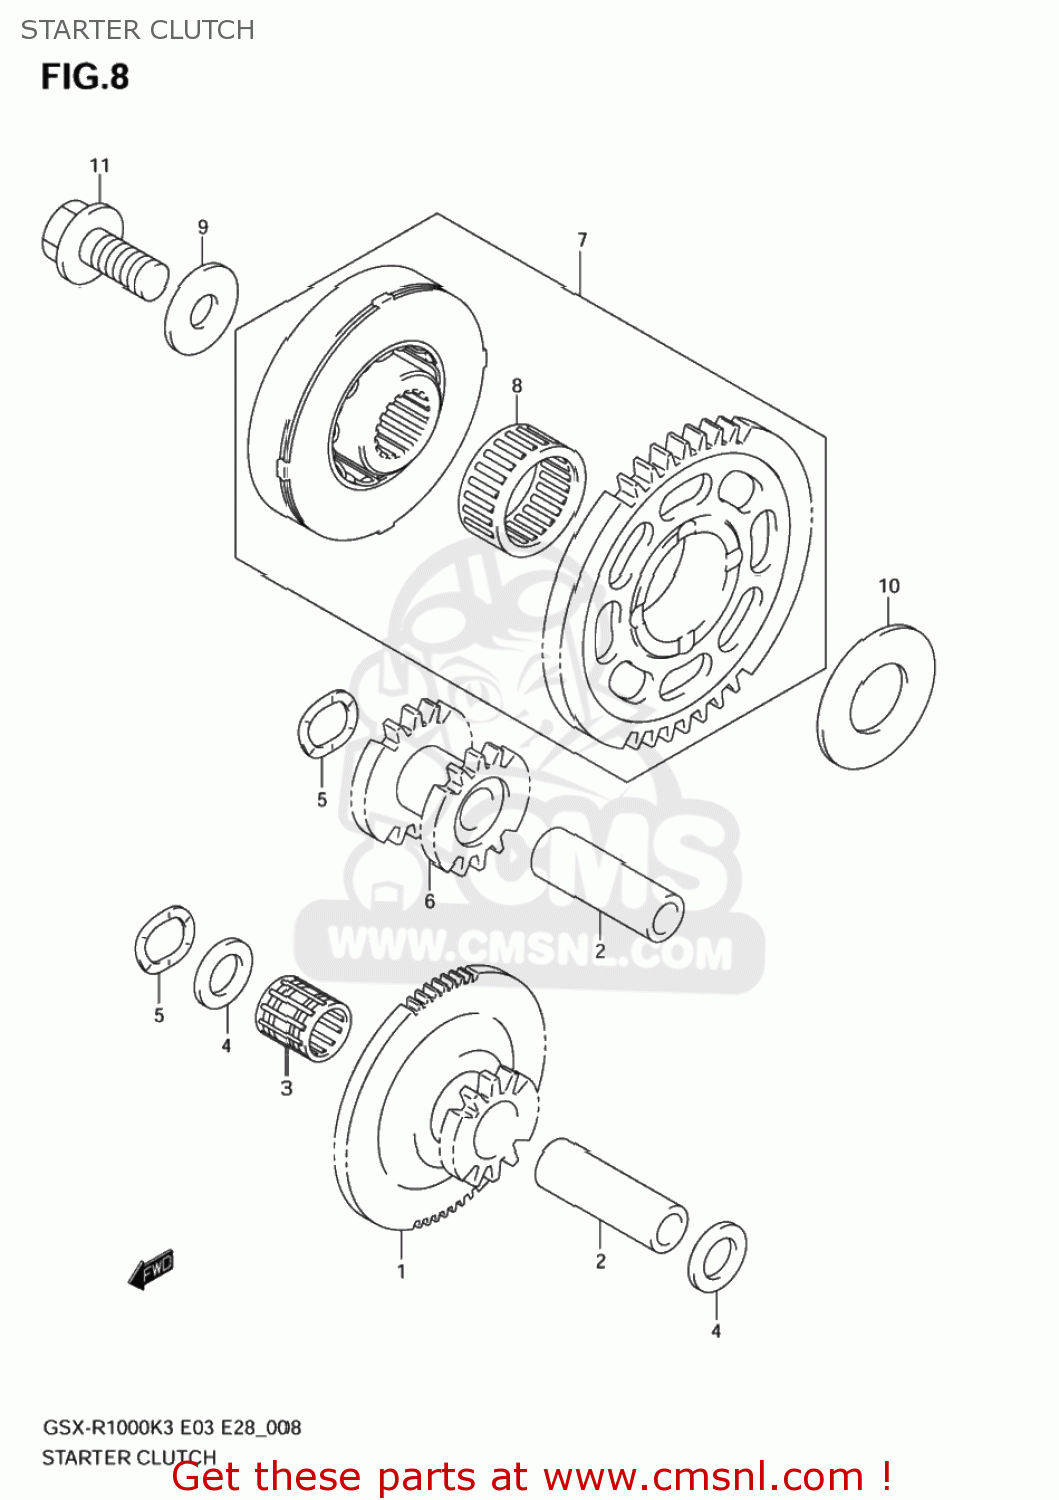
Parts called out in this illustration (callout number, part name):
1	GEAR,STARTER IDLE NO.1
2	PIN,PISTON
3	BEARING(12X16X16)
4	SHIM(12X20X1)
5	WASHER
6	GEAR,STARTER IDLE NO.2
7	CLUTCH SET,STA
8	BEARING(26X31X16)
9	WASHER
10	WASHER
11	BOLT(10X23)
